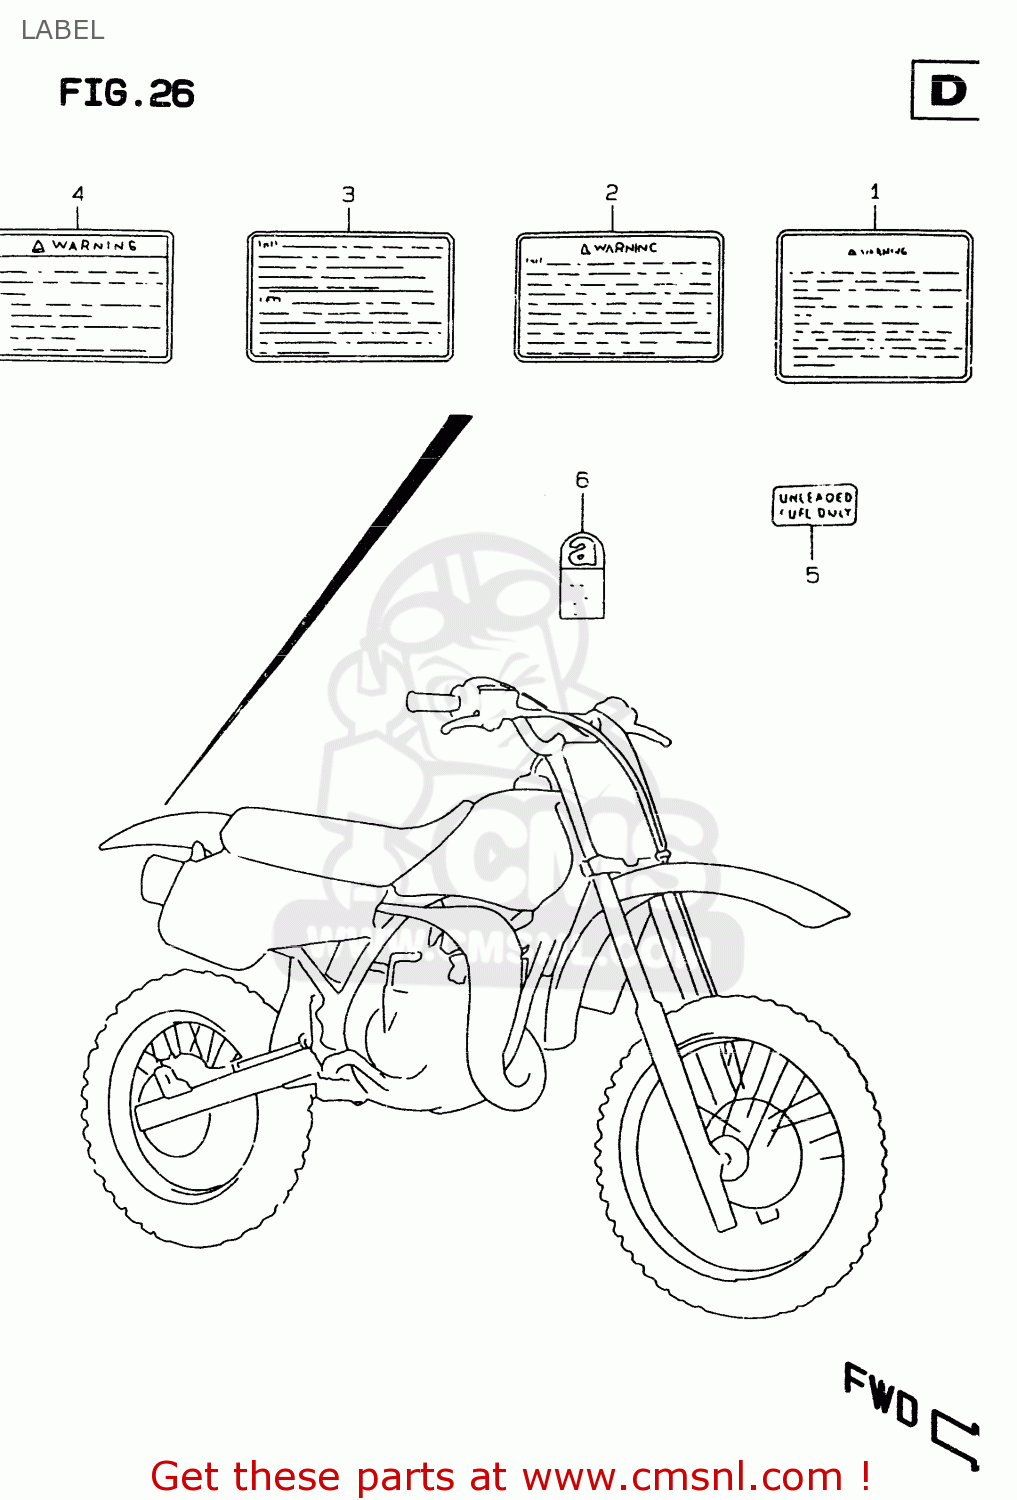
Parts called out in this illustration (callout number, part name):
1	LABEL,WARNING
2	LABEL,WARNING
3	LABEL,WARNING
4	LABEL,WARNING
5	LABEL,UNLEADED FUEL
6	LABEL,ASBESTOS WARNING
7	MANUAL, OWNER'S
